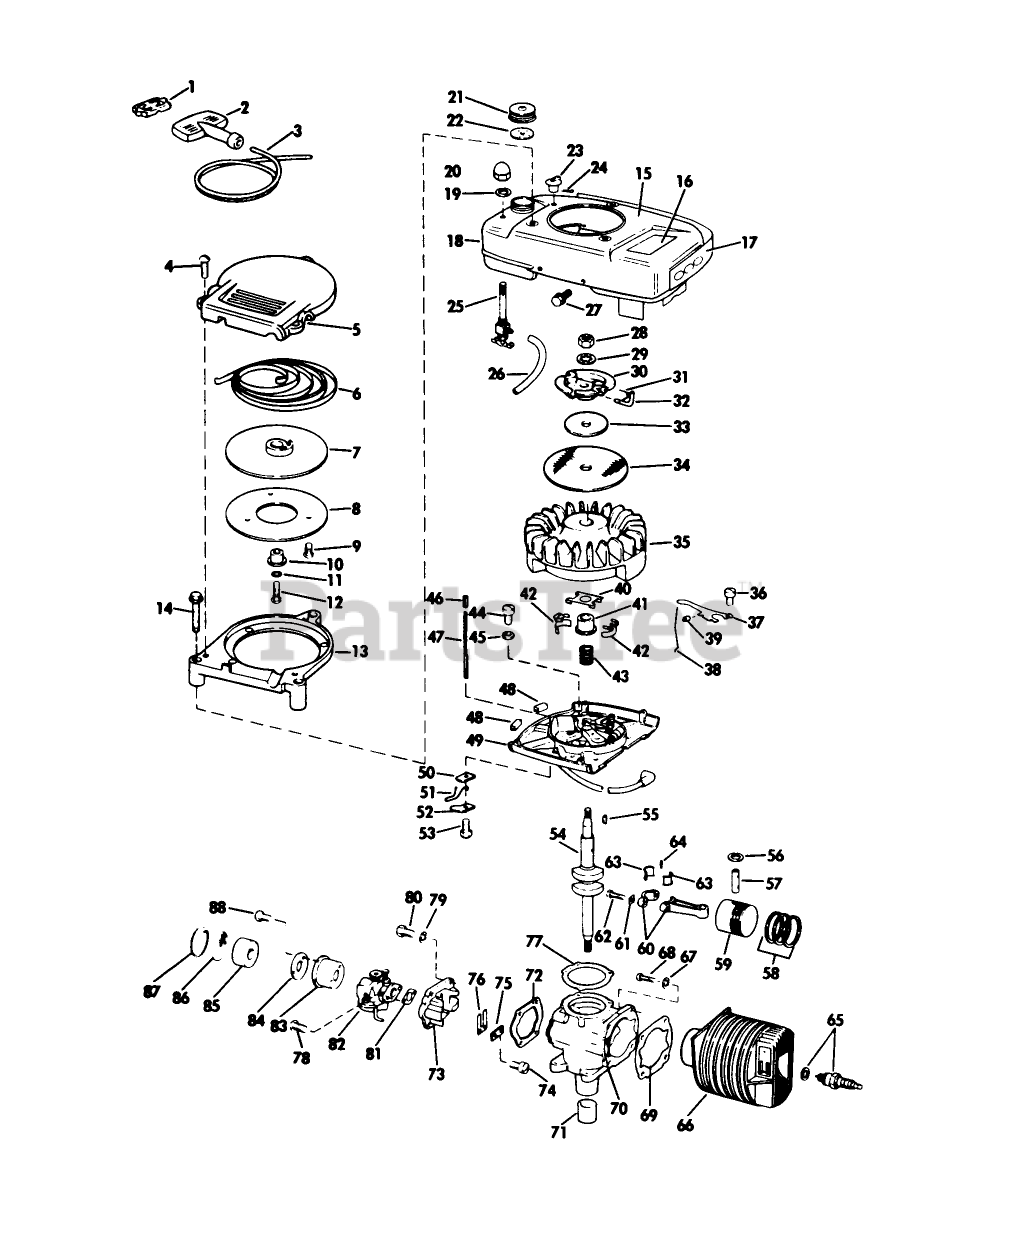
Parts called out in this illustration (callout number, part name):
6	RECOIL SPRING
19	PALNUT S
21	Gas Cap
23	KNOB, CHOKE BAR
24	Cotter Pin-Choke Knob
25	VALVE&SCREEN SM
27	SCREW S
32	PIN - STARTER
37	GOVERNER LEVER AY
38	GOVERNOR ROD S
39	WEAR BLOCK S
41	COLLAR S
53	Screw Shut-off Switch
56	RING-RETAINING
63	LINER ASM
69	GASKET S
75	PLATE-BACKUP, REED
77	GASKET S
80	SCREW S
81	GASKET S
84	BACK-UP PLATE
85	ELEMENT
